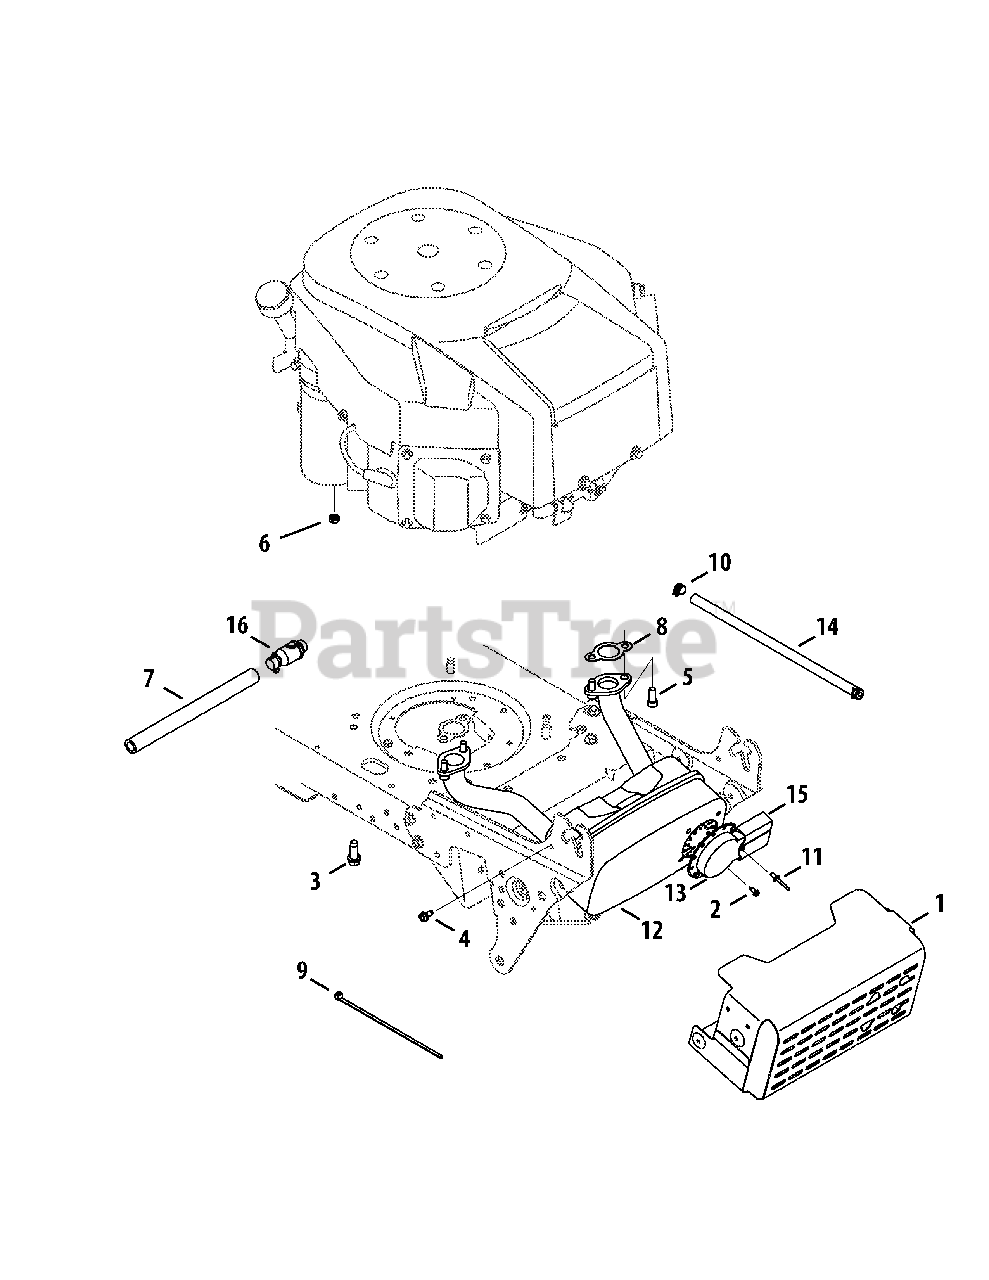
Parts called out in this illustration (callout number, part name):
2	Screw, Ab, #8-18, 0.500,
3	Screw, Self-tapping, 3/8-16, 1.000,
4	Screw, Self-tapping, 1/4-20, 0.500,
5	Screw, Socket Head, 5/16-18, .750
6	Nut, Sems, 1/4-20
7	Hose, Extension, Oil Drain
8	Gasket, Exhaust
9	Cable, Tie, 3/16 x .05 x 7.4
10	Clamp, Hose, .490 Dia.
11	Rivet, Pop, .188 Dia x .300
12	Muffler, Kohler Twin
13	Deflector, Muffler
14	Hose, Fuel, Low Permeation, 1/4
15	Deflector, Muffler, Long
